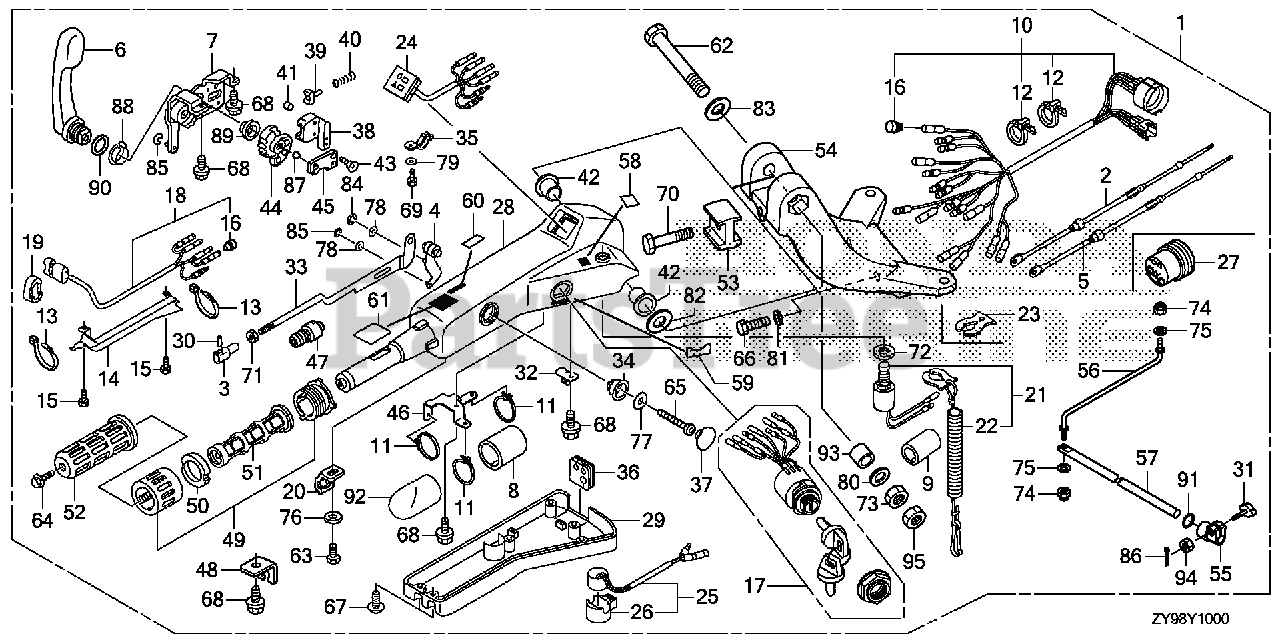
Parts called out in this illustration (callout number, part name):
1	HANDLEBAR KIT *NHB14M* (AQUA MARINE SILVER METALLIC)
2	CABLE, THROTTLE
3	PIVOT, THROTTLE CABLE
4	ARM, THROTTLE
5	CABLE, SHIFT
6	LEVER, SHIFT
7	FRAME ASSY., SHIFT
8	TUBE (38.1X40)
9	TUBE
10	CABLE ASSY., LONG HANDLE (A)
11	BAND (CONVEX CV-150)
12	BAND (CONVEX CV-200)
13	BAND (CONVEX)
14	COVER, WIRE
15	SCREW
16	PLUG, CONNECTOR (INNER)
17	SWITCH ASSY., COMBINATION
18	SWITCH ASSY., POWER TILT
19	GROMMET
20	HOLDER, SWITCH
21	SWITCH ASSY., EMERGENCY STOP
22	WIRE, EMERGENCY
23	CLIP, EMERGENCY LOCK
24	LAMP ASSY., INDICATOR
25	BUZZER ASSY., WARNING
26	SUSPENSION, WARNING BUZZER
27	GROMMET, HANDLEBAR CABLE
28	HOUSING *NHB14M* (AQUA MARINE SILVER METALLIC)
29	COVER, HANDLEBAR (LOWER)
30	PIN, THROTTLE CABLE
31	BOLT, FRICTION
32	BRACKET, CABLE
33	PLATE ASSY., LOCK
34	STOPPER
35	PLATE, GUIDE
36	GROMMET
37	CAP
38	GUIDE, SPRING
39	ACTUATOR
40	SPRING, COIL
41	ROLLER
42	BUSH, HANDLEBAR
43	SCREW (M5X14)
44	GEAR, SHIFT
45	PLATE, BALL GUIDE
46	BRACKET
47	ROD, GROMMET
48	CLAMP, BRACKET
49	GRIP ASSY., THROTTLE FRICTION
50	PAD, THROTTLE FRICTION
51	PIPE, GRIP
52	RUBBER, GRIP
53	BLOCK, HEIGHT ADJUSTER
54	BRACKET B, STEERING *NHB14M* (AQUA MARINE SILVER METALLIC)
55	BLOCK, STEERING FRICTION
56	ROD, STEERING FRICTION
57	SHAFT, STEERING FRICTION
58	MARK, EMERGENCY SWITCH INDICATION (EU)
59	MARK, STARTER (ENGLISH)
60	MARK, CHANGE
61	MARK, THROTTLE (ENGLISH)
62	BOLT, HEX. (12X80)
63	BOLT (M5X8)
64	BOLT, FLANGE (6X12)
65	BOLT (M8X50)
66	BOLT, HEX. (10X32)
67	BOLT (M5X12)
68	BOLT (M6X12)
69	BOLT (M5X12)
70	BOLT, FLANGE (8X28)
71	NUT, HEX. (5MM)
72	NUT, HEX. (16MM)
73	NUT, HEX. (12MM)
74	NUT, SELF-LOCK (8MM)
75	WASHER, PLAIN (8MM)
76	WASHER (5MM)
77	WASHER (8MM)
78	WASHER (10MM)
79	WASHER (5MM)
80	WASHER, WAVE (14MM)
81	WASHER (10MM)
82	WASHER, PLAIN (12MM)
83	WASHER, PLAIN (12MM)
84	E-RING
85	E-RING
86	PIN, SPLIT (2.0)
87	BALL, STEEL
88	BEARING
89	BEARING
90	O-RING (20.6X1.9)
91	O-RING (15.54X2.62)
92	TUBE, CORD (40MM)
93	COLLAR, DISTANCE (12.2X23X16)
94	NUT, HEX. (6MM)
95	NUT, HEX. (12MM)
